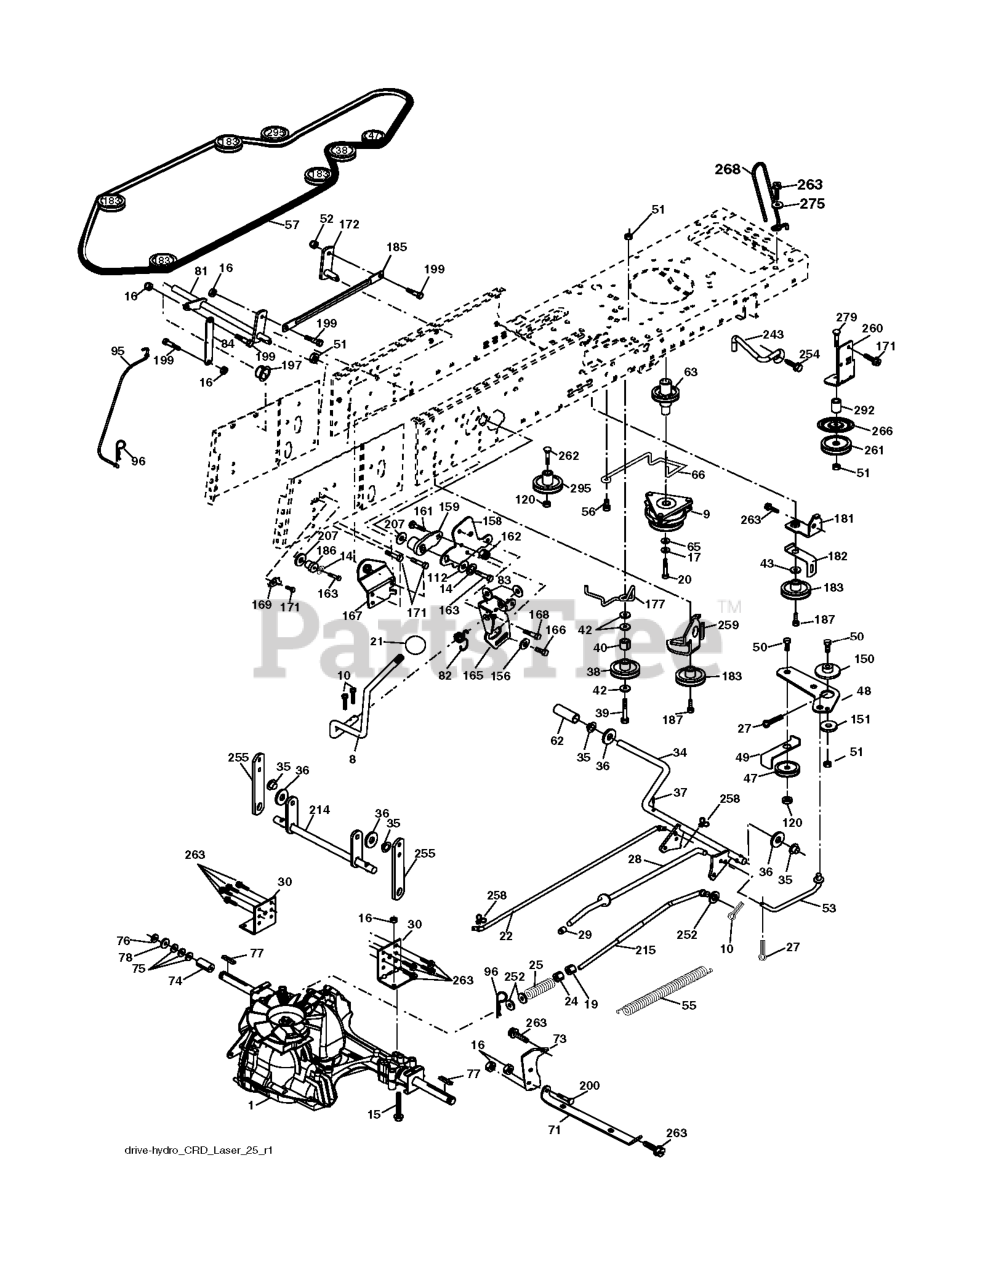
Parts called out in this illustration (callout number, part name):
8	ROD SHIFT FENDER ADJUST LT
9	CLUTCH.ELECTRIC.OGURA.EURO.
10	PIN COTTER
14	LOCKWASHER
15	BOLT HEX 5/16-18 GR 5
16	NUT.71038.31-18.HEX.NYLOCK
19	NUT
20	BOLT HEX 7/16-20X4-1/4"
21	KNOB.DUCKHEAD.1/2
22	ROD
24	NUT
25	SPRING BRAKE ROD
27	COTTER PIN
28	ROD, PARKING BRAKE
29	CAP
30	BRKT, TRNSXLE MNT 20"
34	SHAFT, FOOT PEDAL
35	BEARING.NYLON
37	DRIVE PIN
38	PULLEY.FLAT
42	WASHER
47	IDLER PULLEY
48	BELLCRANK, CLUTCH
49	RETAIN BELT
50	BOLT.3/8-16X1.50
52	LOCKNUT
53	LINK.CLUTCH.7.66.2005
55	SPRING, RETURN LT
56	SCREW.3/8-16
57	V-BELT 113"
62	PEDAL COVER T
63	PULLEY.ENGINE.CVX.LT
65	LOCKWASHER
66	KEEPER BELT ENGINE
71	STRAP TORQUE LH HYDRO
73	STRAP TORQUE RH HYDRO
74	SPACER AXLE
77	SQUARE KEY
81	ASM.CROSS.SHAFT.REAR.CRD.0510
82	SHIFT SPRING
83	WASHER
84	LINK.PNT.TRANSAXLE.0510.CRD
95	LINK
96	RETAINER M
120	NUT LOCK FLG 3/8-16 UNC
150	BUSHING.BELLCRANK.GRD.DR
151	WASHER 12/32X2X10GA
156	WASHER.SRRTD.5/16
158	BRACKET
159	RB HUB.SHIFT
161	BOLT
162	NUT.CROWNLOCK.1/4
165	RP BRACKET
166	CAPSCREW.HXHD.FLG.5/16-18X.625
167	BRACKET.SUPT.SHIFT.CRD
168	BOLT.SHOULDER.5/16-18X
169	PLATE.FASTENING.CROSS.SHAFT
172	LINK
181	BRACKET
182	BELT GUIDE
183	PULLEY.V-IDLER.GRND.DR
185	LINK
186	HUB.TAPERED.ROUND.CRD
187	BOLT.5/16-18X1.25
197	NYLINER SNAP 5/8" ID
199	BOLT SHOULDER 5/16-18 UNC
207	WASHER NYL
214	LEVER
215	ROD
243	BRACKET, ANTI-ROTATION
252	WASHER
254	SCREW 3/8-16X1
255	SHAFT
258	CLIP RETAINER
259	BRACKET
261	FLAT IDLER PULLEY
263	SCREW, 3/8-16X3/4
266	PROTECTOR
268	GUARD MUFFLER
275	WASHER
292	SPACER
295	PULLEY IDLER COMPOSITE
